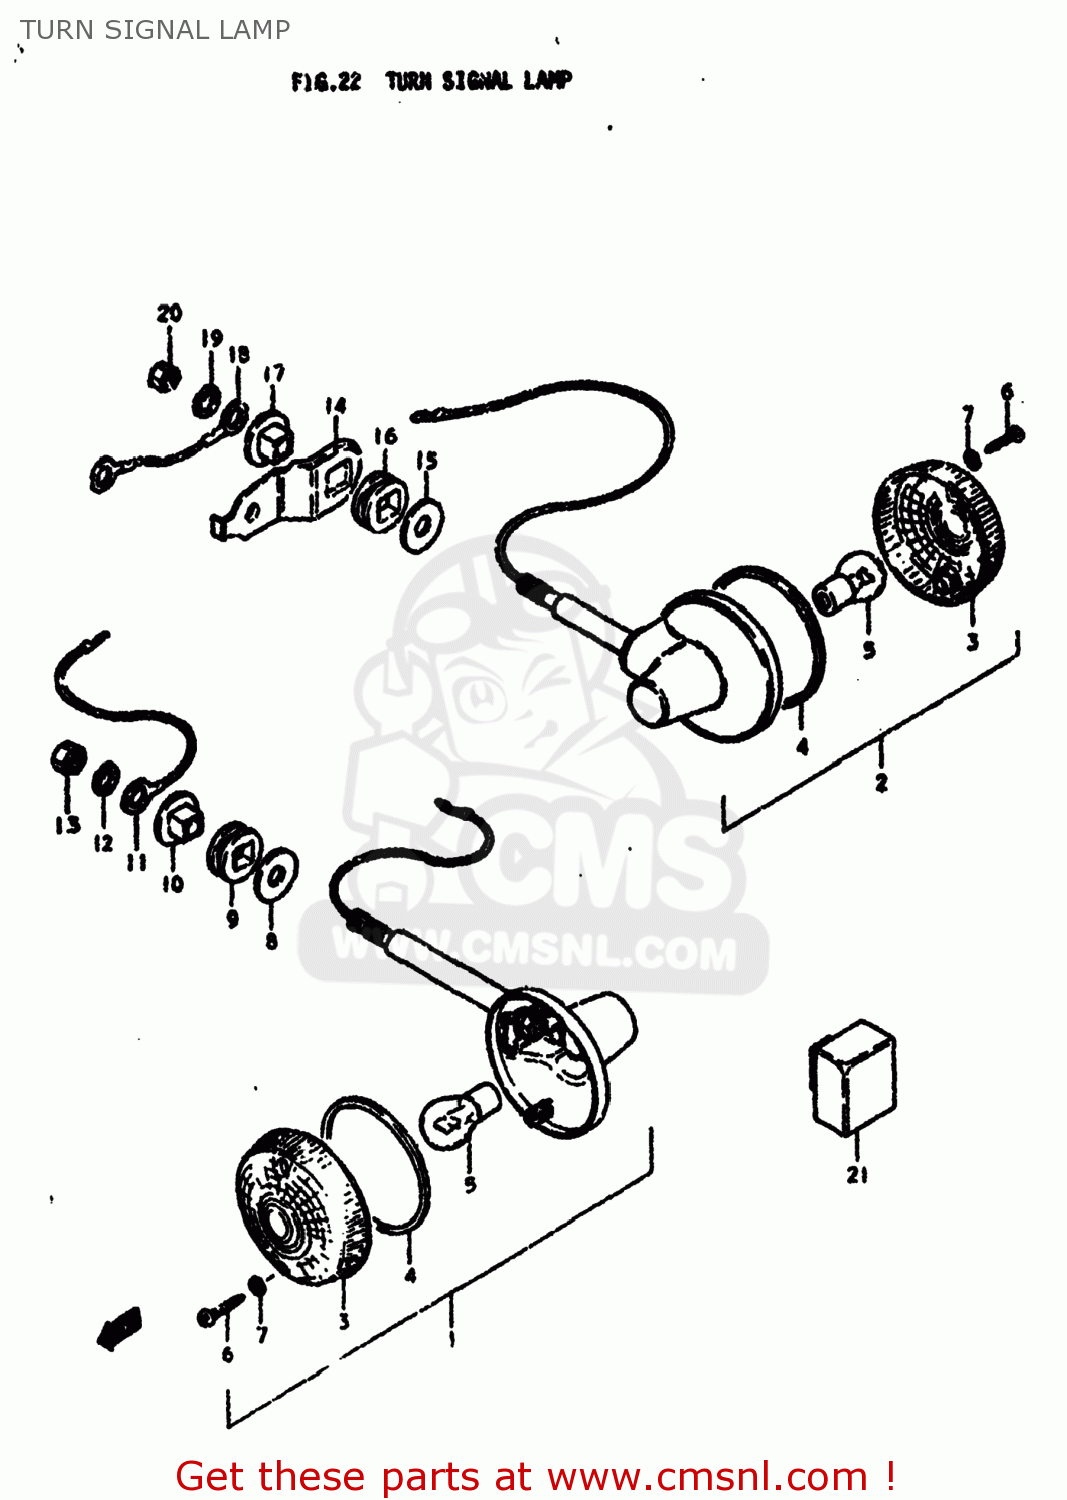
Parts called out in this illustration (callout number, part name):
1	LAMP ASSEMBLY,FRONT TURN SIGNAL
2	LAMP ASSEMBLY,REAR TURN SIGNAL
3	LENS
4	GASKET (NAS)
5	BULB(6V17W,STANLEY,A4513A)
6	SCREW
7	GASKET (NAS)
8	WASHER (10.5X30X2.3)
9	CUSHION
10	SPACER,TURN SIGNAL LAMP
11	LEAD WIRE,EARTH
12	LOCK WASHER
13	NUT
14	BRACKET,REAR TURN SIGNAL
15	WASHER (10.5X30X2.3)
16	CUSHION
17	SPACER,TURN SIGNAL LAMP
18	LEAD WIRE,EARTH
19	LOCK WASHER
20	NUT
21	RELAY,TURN SIGNAL
